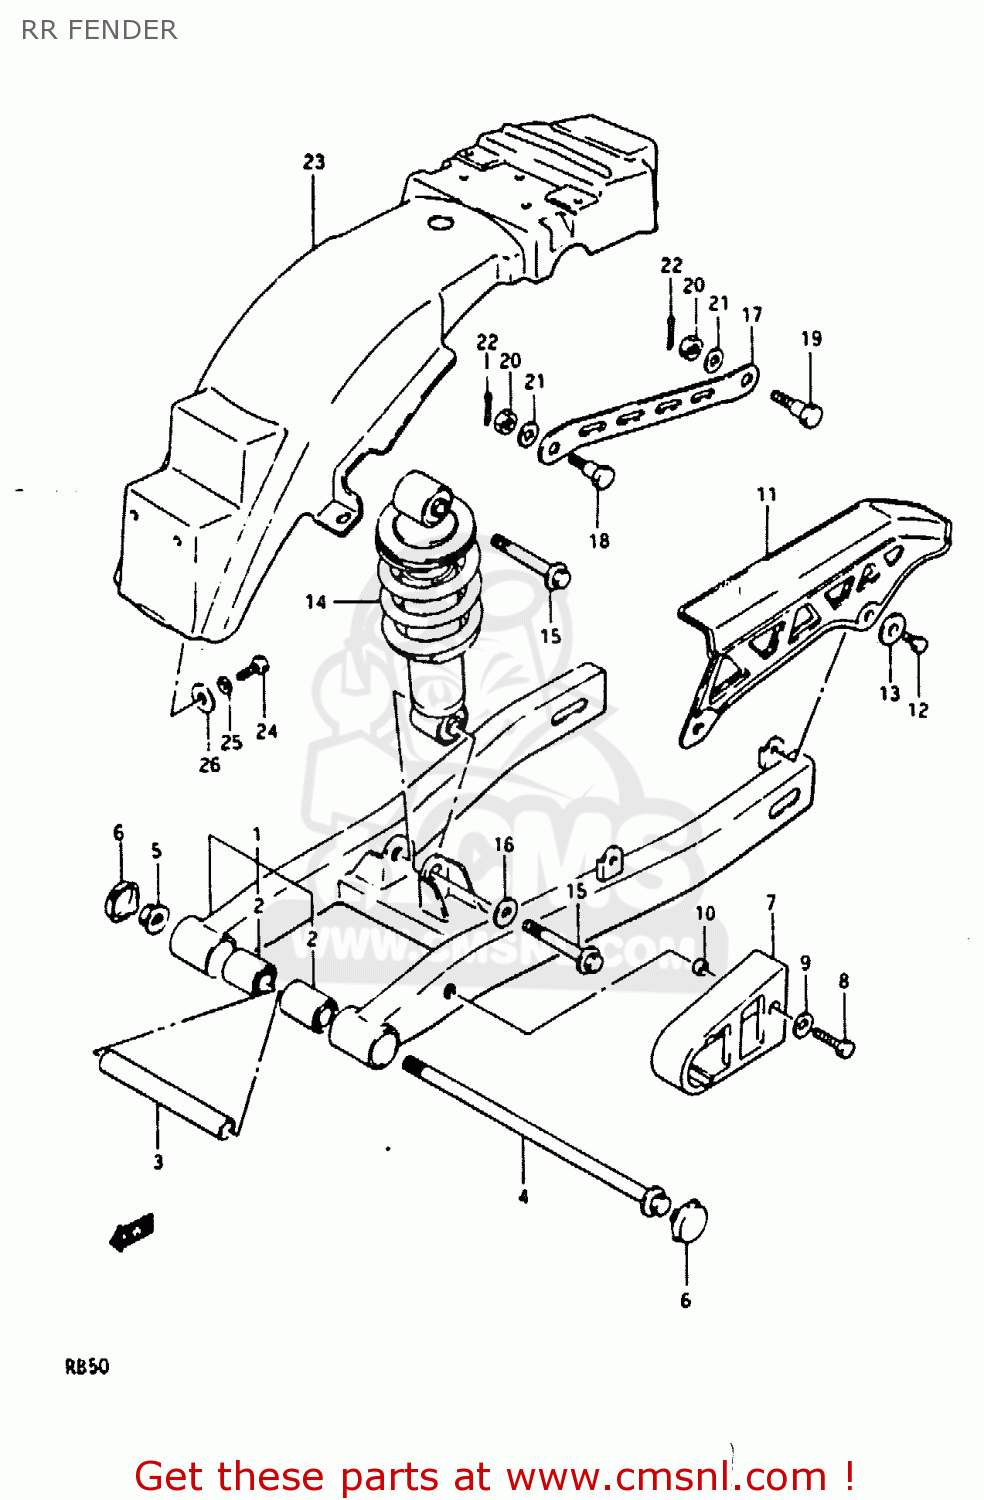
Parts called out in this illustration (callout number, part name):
1	SWING ARM SET,REAR
2	BUSHING(10X23X35)
3	SPACER (10.2X17X107)
4	SHAFT,REAR SWING ARM PIVOT
5	NUT
6	CAP,SWINGINGARM PIVOT
7	BUFFER,CHAIN TOUCH DEFLECTOR
8	BOLT,M6X1X20
9	WASHER(6.5X16X1.2)
10	SPACER
11	CHAIN CASE
12	BOLT 6X8
13	WASHER
14	ABSORBER ASSEMBLY,REAR SHOCK
15	BOLT,RR SHOCK ABSORBER(10X51)
16	WASHER
17	TORQUE LINK,REAR
18	BOLT(8X22)
19	BOLT(8X26.5)
20	NUT
21	LOCK WASHER
22	PIN 20X20
23	FENDER,REAR
24	BOLT
25	WASHER,LOCK
26	WASHER (6.5X20X1.2)
